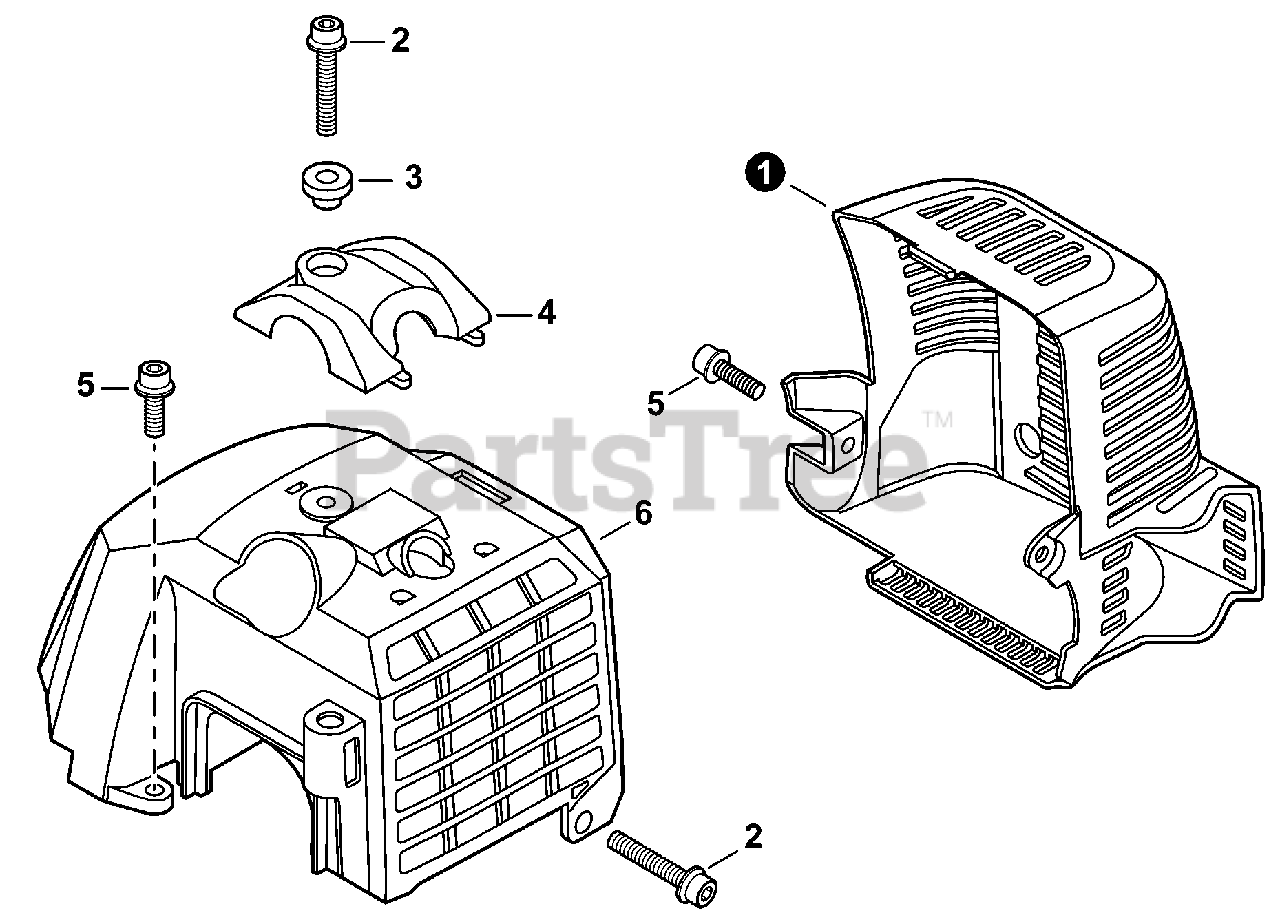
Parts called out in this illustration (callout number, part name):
1	COVER, MUFFLER
2	BOLT 5×20
3	COLLAR 5
4	GUARD, TOP
5	BOLT 5×12
6	COVER, ENGINE
